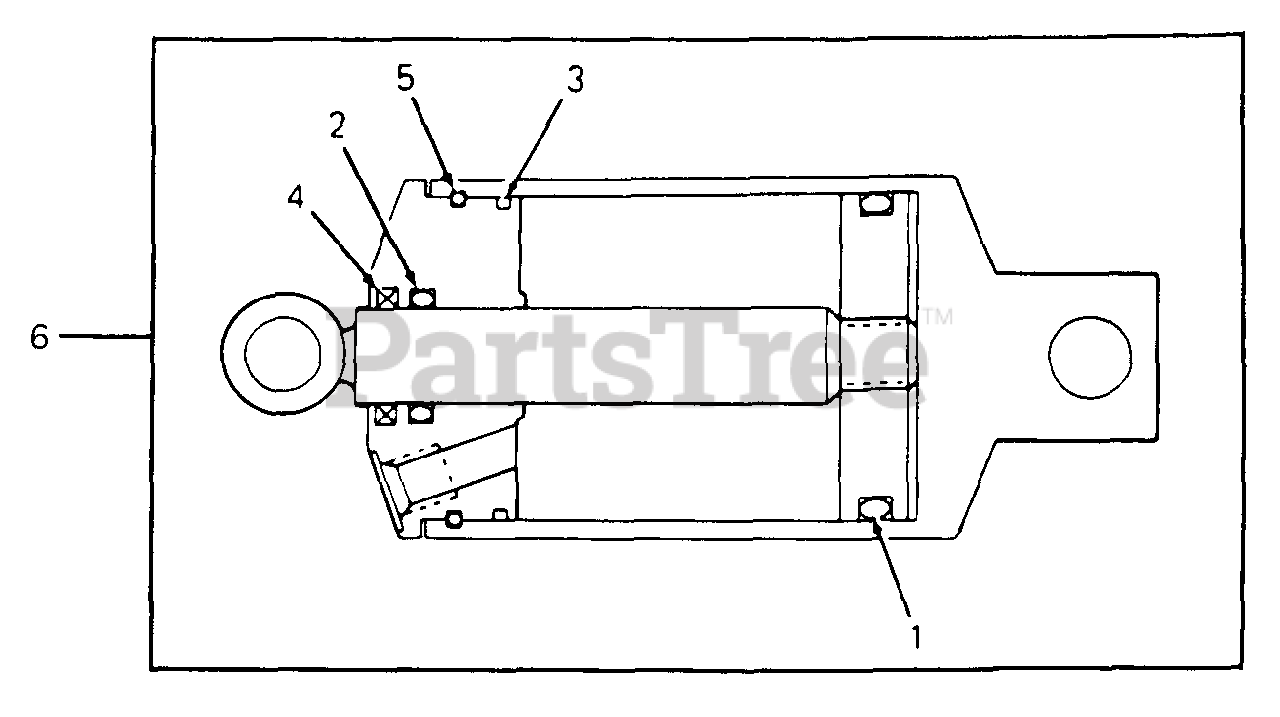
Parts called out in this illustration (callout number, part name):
4	Seal, Hydraulic Cylinder Piston Rod Wiper
5	Retainer, Hydraulic Cylinder Front Head
6	Cylinder, Hydraulic
